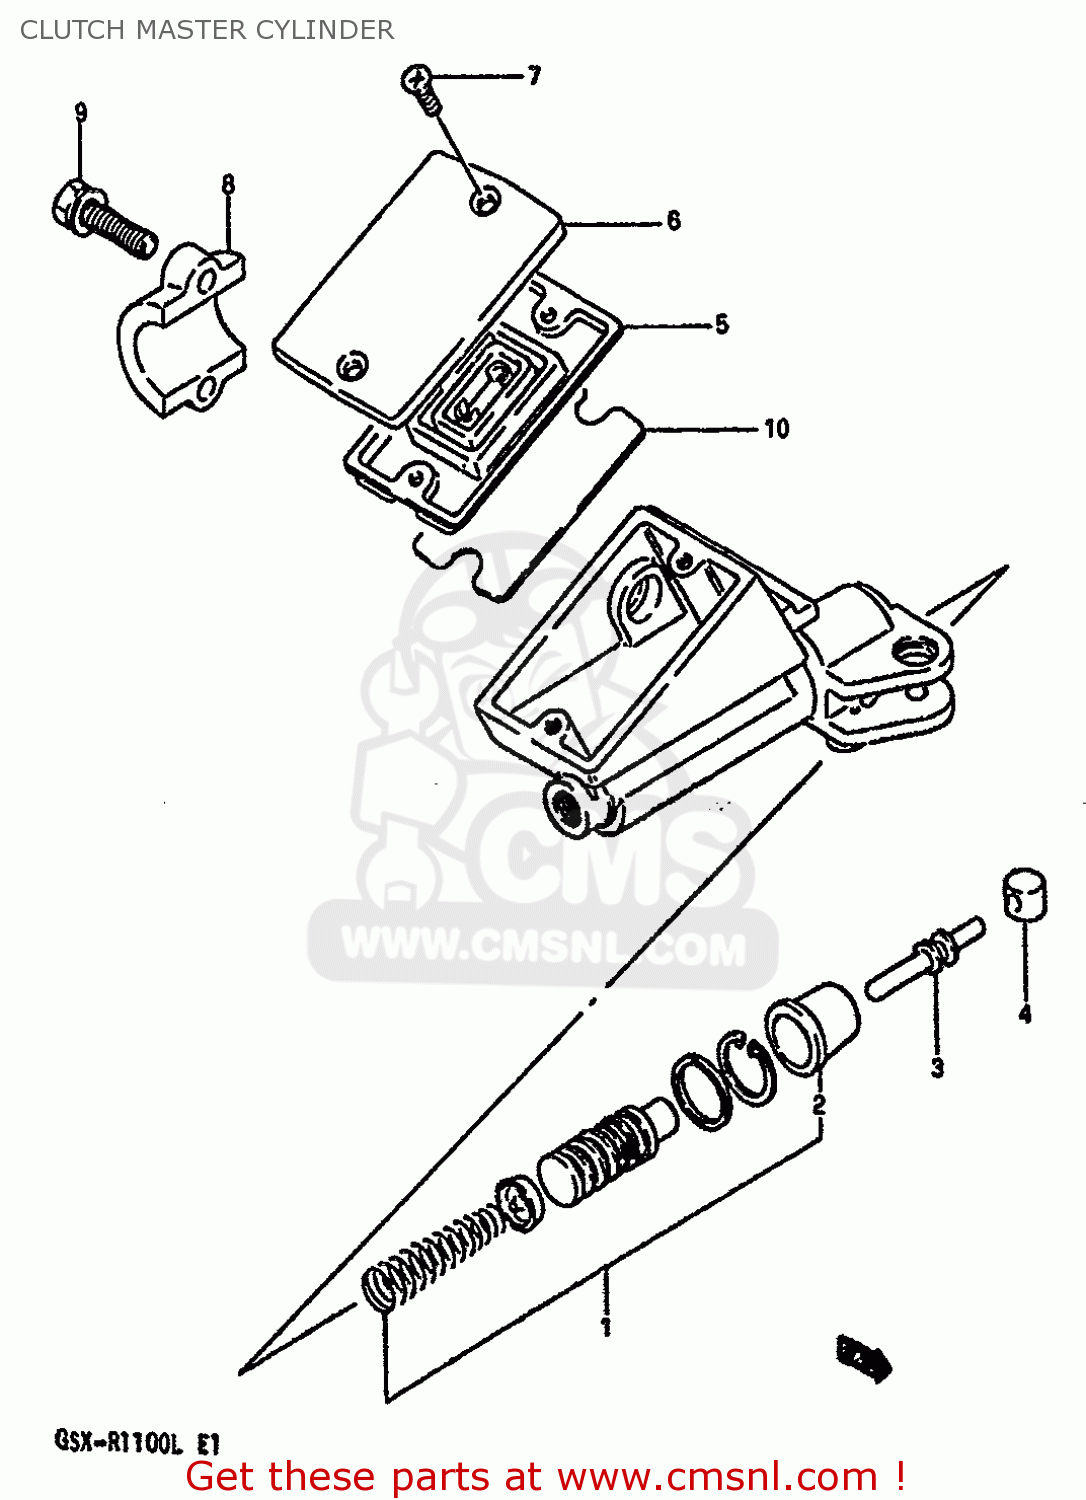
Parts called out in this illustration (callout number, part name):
1	PISTON & CUP SET
2	BOOT
3	ROD,PUSH
4	BUSH
5	6-1
6	CAP
7	SCREW
8	HOLDER
9	BOLT
10	FLOAT
